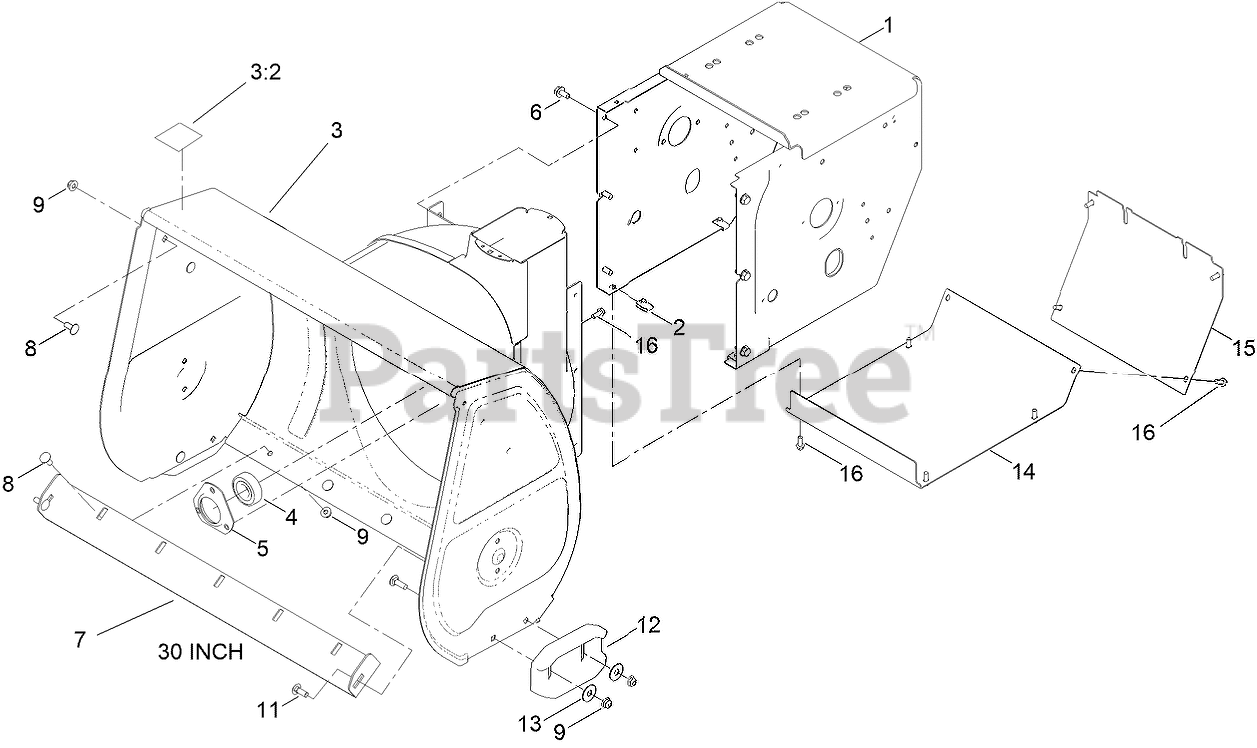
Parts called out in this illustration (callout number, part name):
1	FRAME-TRACTION
3	AUGER HOUSING ASM (W/DECAL 30")
3:2	DECAL-DANGER, AUGER
4	BEARING-BALL
5	RETAINER-BEARING
6	SCREW-HWHTF
7	SCRAPER, 30"
8	BOLT-CARR
9	NUT-HF
11	BOLT-CARR
13	WASHER-FLAT
14	COVER-BOTTOM
15	COVER-REAR
16	SCREW-HWH
